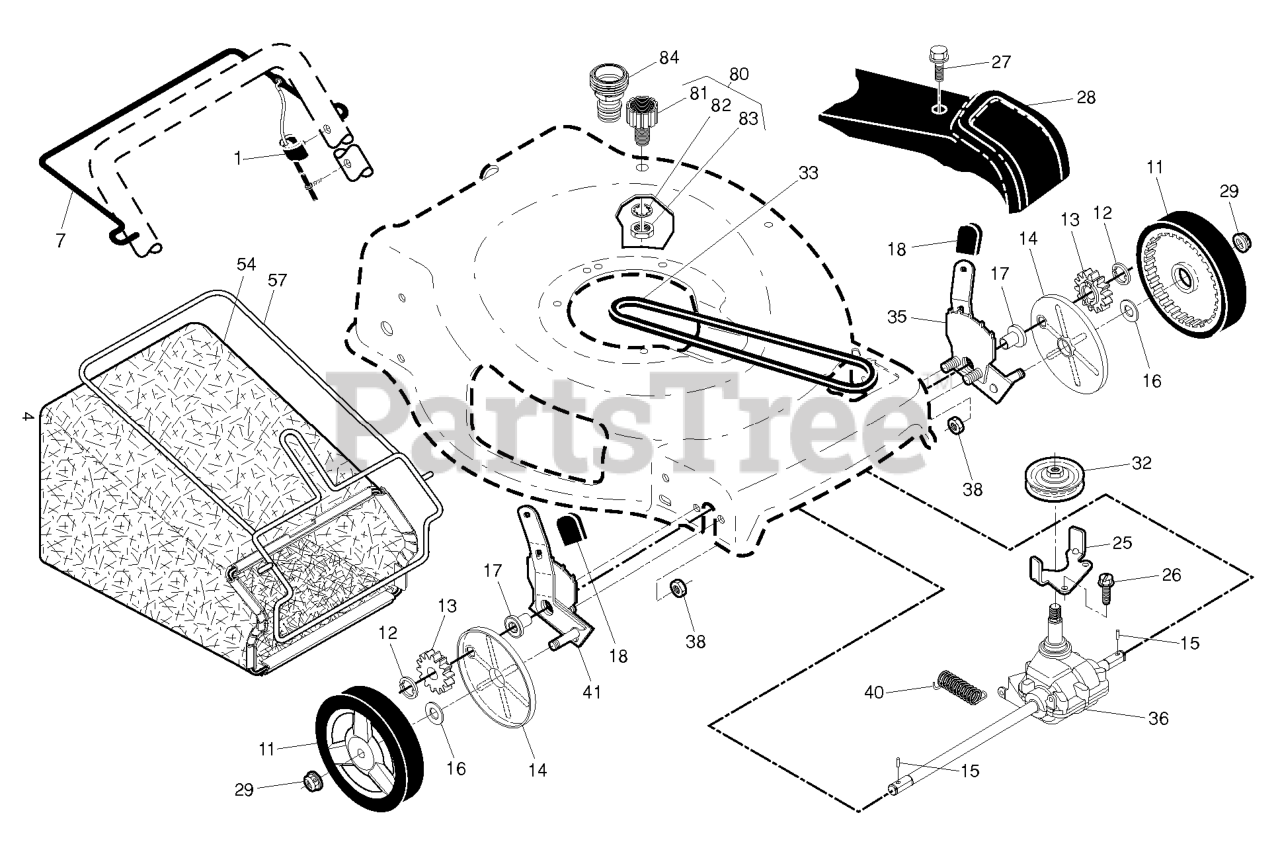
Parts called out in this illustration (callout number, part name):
1	CABLE.DRIV.DUAL.LEVER.BAIL.FGD
7	BAIL.CONT.DR.S/S.ROUND.BLACK
11	WHEEL.8X1.75.H3SPK.RAD3.GY.BU3
12	E-RING 7/16 RE
13	PINION.14.TEETH.FGD
14	COVER.DUST.WHEEL.INNER.WALK
15	PAWL, DRIVE
16	WASHER FLUT
18	SELECTOR KNOB
25	BRACKET.BELT.GUIDE.22+FGD.BZP
27	SCREW, HEX HD TAPPING #10-24 1
28	COVER.DRIVE.22.LABEL.HUSQVARNA
29	NUT.HEX.FLANGE.3/8-16.LO(3 2)
32	RP PULLEY.DRIVE.EZ/VAR.SCREWON
33	BELT.DRIVE.FGD.
35	ADJUSTER.ASM.9.22+/RF/LR.21/RF
36	RP.TRANSMISSION.22+.FWGD.SS
38	NUT.HEX.FLANGE.1/4
41	ADJUSTER.ASM.9.22+/RF/LR.21/LF
54	GBAG.A3610247T.SILV.HUSWT.BLUE
57	RB FRAME.GBAG.22PLUS
80	KIT.WASH-OUT.PORT.ZINC.WALK
81	WASHOUT.PORT.ZINC.RGD.22+
82	WASHER.LOCK.INTERNAL.TOOTH
83	LOCKNUT.HEX.WITH.O-RING
84	COUPLING.QUICK CONNECT
